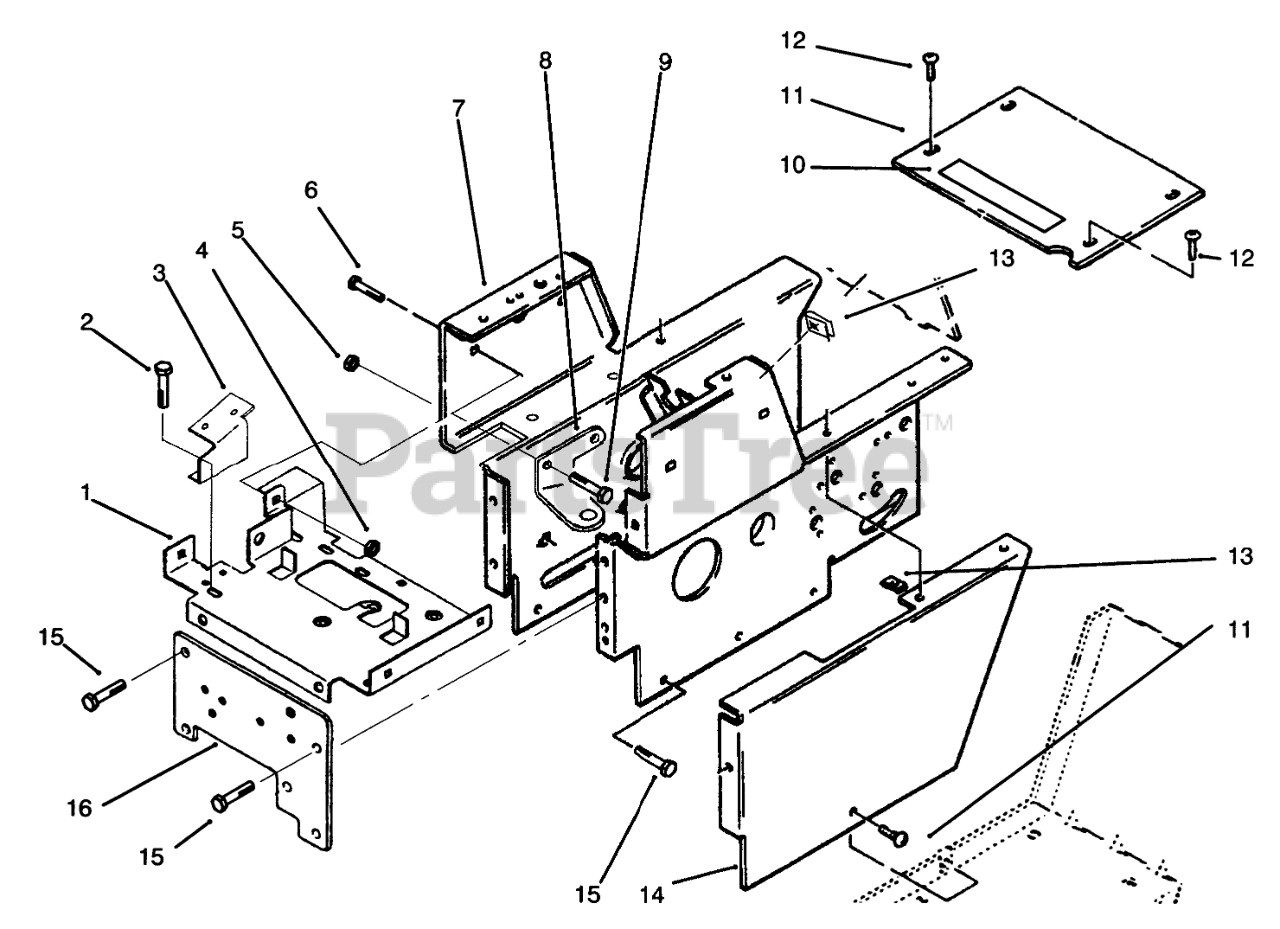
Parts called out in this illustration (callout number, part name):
1	SUPORT-BATERYB
2	SCREW-HWH
3	BRACKET-SWITCH
4	Nut
5	NUT-LOCK, NI
6	BOLT CARR. 5/16X1/2 BK
7	Hoodstand
8	Bracket-Control
9	SCREW-HH
10	STRG-WHL INSERT TORO
11	Plate-Shift Cover (Incl. Ref. #10)
12	SCREW-PPH
14	Cover-Side LH
15	Bolt
16	Front Plate
